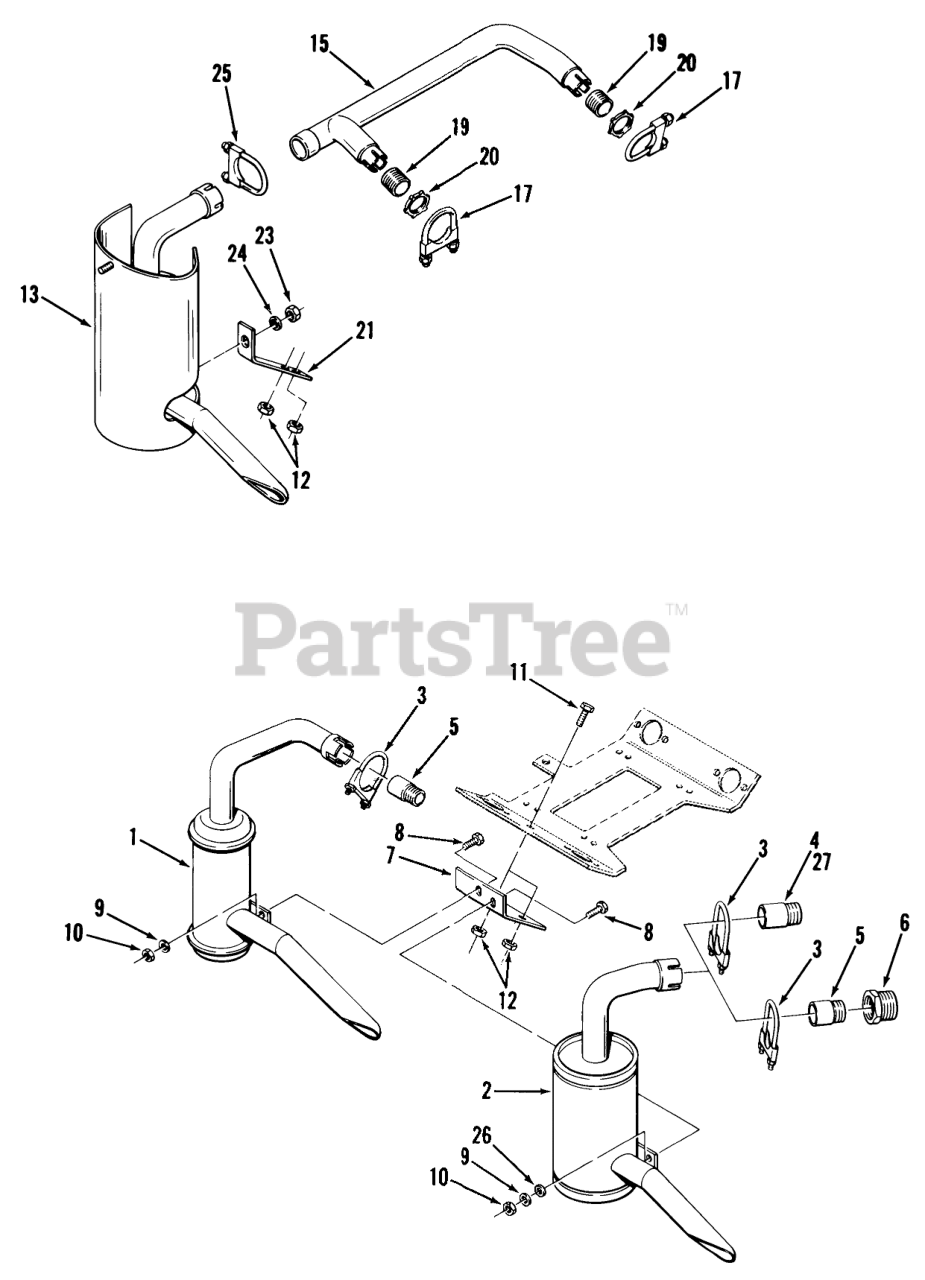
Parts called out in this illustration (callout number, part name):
1	ASSY-MUFFLER
2	MUFFLER ASSEMBLY
2	Muffler C-111 Only
3	ASSY-MUFFLER CLAMP
4	NIPPLE
5	NIPPLE- 1X2 SPECIAL
6	REDUCER 1 1/4-1
7	BRACKET-MUFFLER MTG
8	H H C S
9	Washer
10	Nut
11	Bolt
12	Nut
13	ASSY-MUFFLER
15	Exhaust Manifold C-161 Twin Only
17	ASSY-MUFFLER CLAMP
19	NIPPLE-EXHAUST
20	LOCKNUT-CONDUIT
21	Muffler Mounting Bracket C-161 Twin Only
23	Nut
24	LOCKWASHER
25	ASSY-MUFFLER CLAMP
27	Lock Nut
